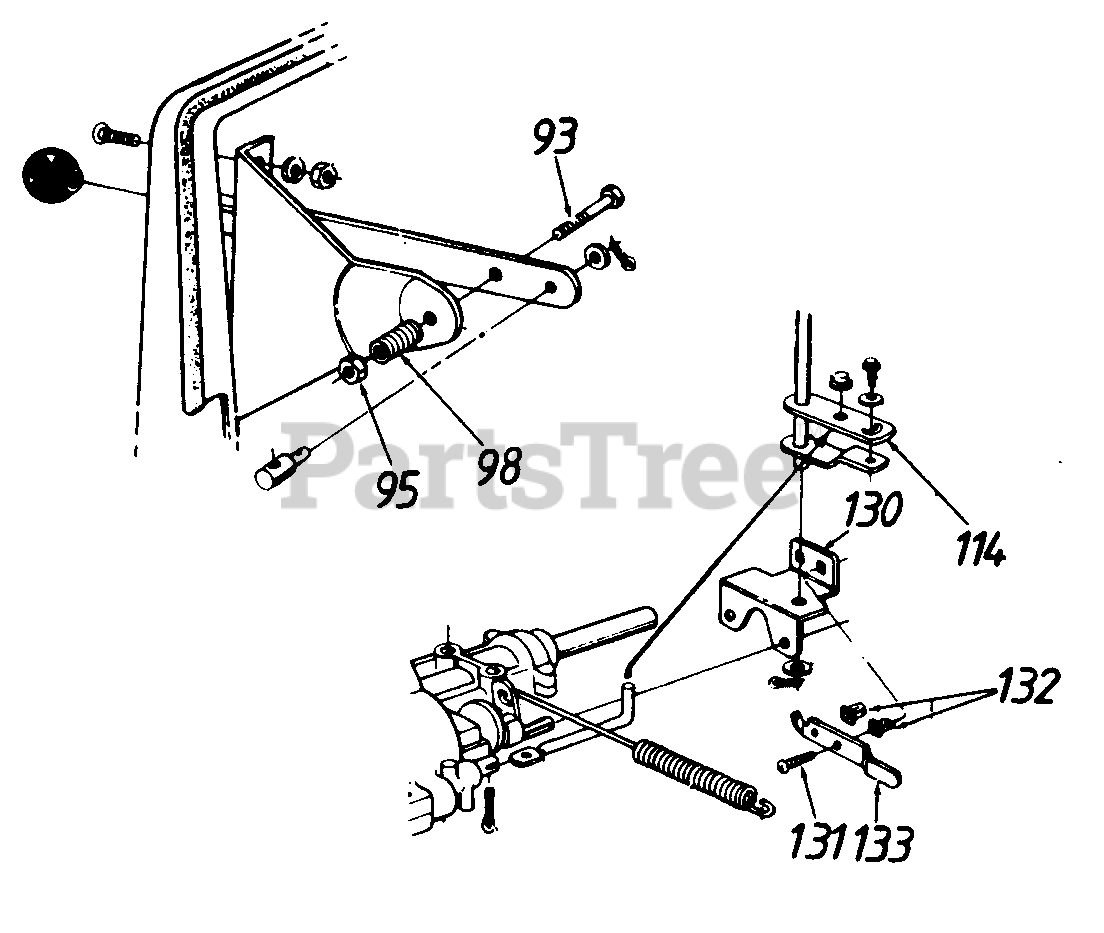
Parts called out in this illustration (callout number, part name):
93	Hex Bolt 1/4-28 x 1.5" Lg.
95	Hex L-Nut 1/4-28 Thd.
98	Comp. Spring 1" Lg.
114	Shift Lever Adjusting Link
130	Shift Lever Support
131	Countersunk AB Tap Scr. #8 x .5" Lg.
132	Push Nut
133	Spring Switch
